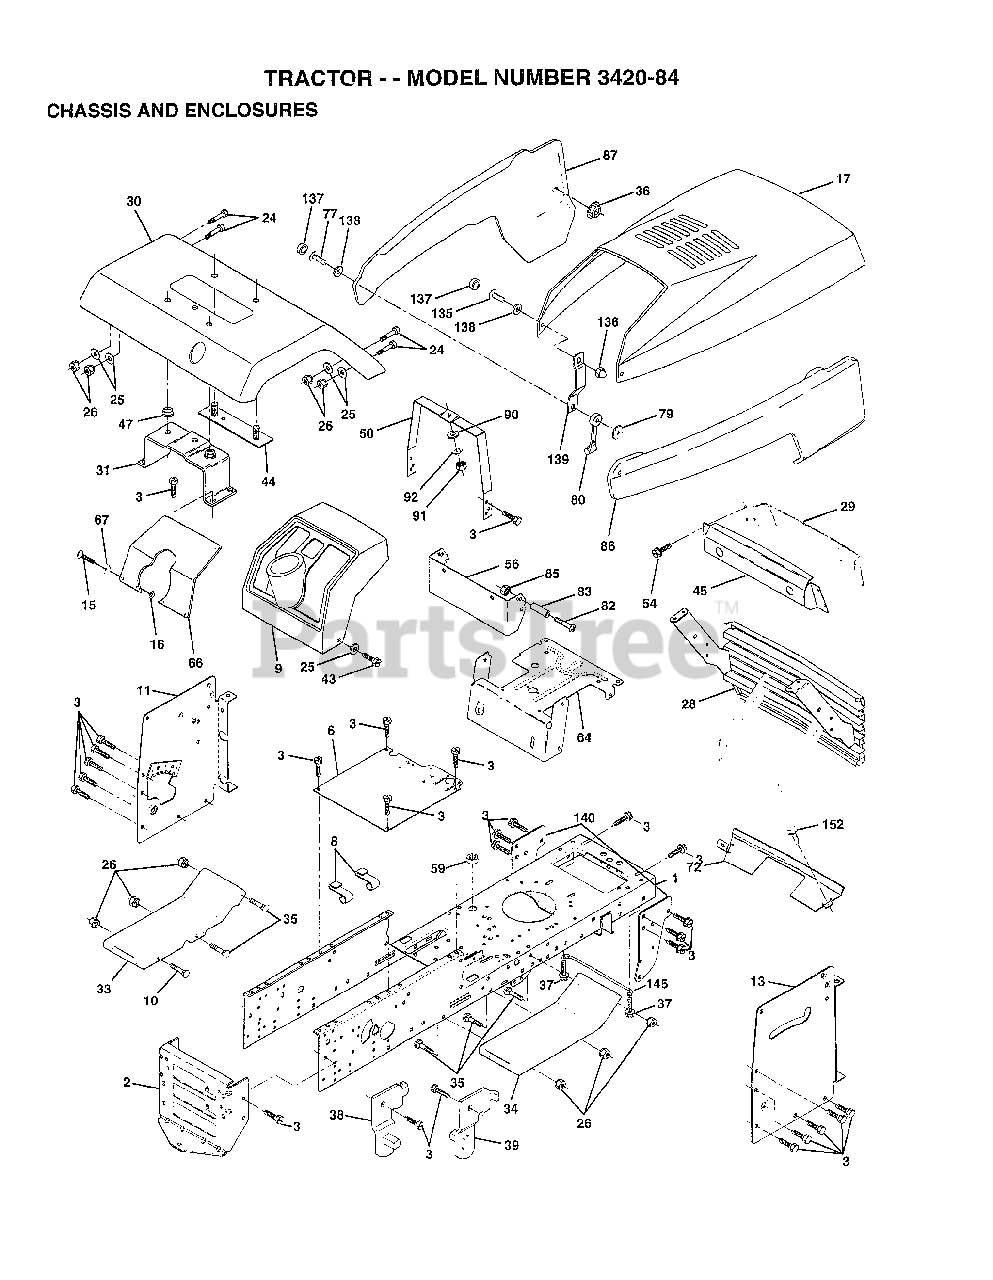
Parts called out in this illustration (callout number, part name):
3	SCREW
6	SADDLE
8	"CLIP,INSULATOR"
9	DASHBOARD BLACK
11	PANEL.DASH.LH.PNT
13	PANEL.PNT.DASH.RH
15	SCREW
24	BOLT
25	WASHER
26	NUT
28	GRILLE ASM PNT
29	PANEL.DASH.RH
31	BRKT.ASM.FENDER
33	FOOTREST.LH.LT/GT
34	FOOTREST.RH.LT/GT
35	BOLT
36	PAL NUT LT
37	SCREW LT
38	BRACKET ASM LH
39	BRACKET ASM RH
43	SCREW GTV
44	STRAP ASM FENDER
45	BEZEL.ASM.
47	NUT-PUSH YT
50	DASH.SUPT.YP/HUSQ
54	SCREW.HEX.WS.HD
56	EXT DASH LTYT
64	DASH.LOWER.LT
66	"PLATE-DASH,SLKSCR"
67	WASHER
72	STRAP.GRILLE.424
77	SCREW
79	WELDNUT
80	HOOD LATCH T
82	SCREW
83	SPACER LT
90	WASHER PM
92	LOCKWASHER
135	SCREW.10-24X3/8.
136	ACORN NUT RB
137	SNAP CAP LT
138	WASHER LT
139	BKT.SPT.HOOD/PANL
140	BRKT SUSPENSION
145	"ROD POVOT,CHASSIS"
152	SCREW
